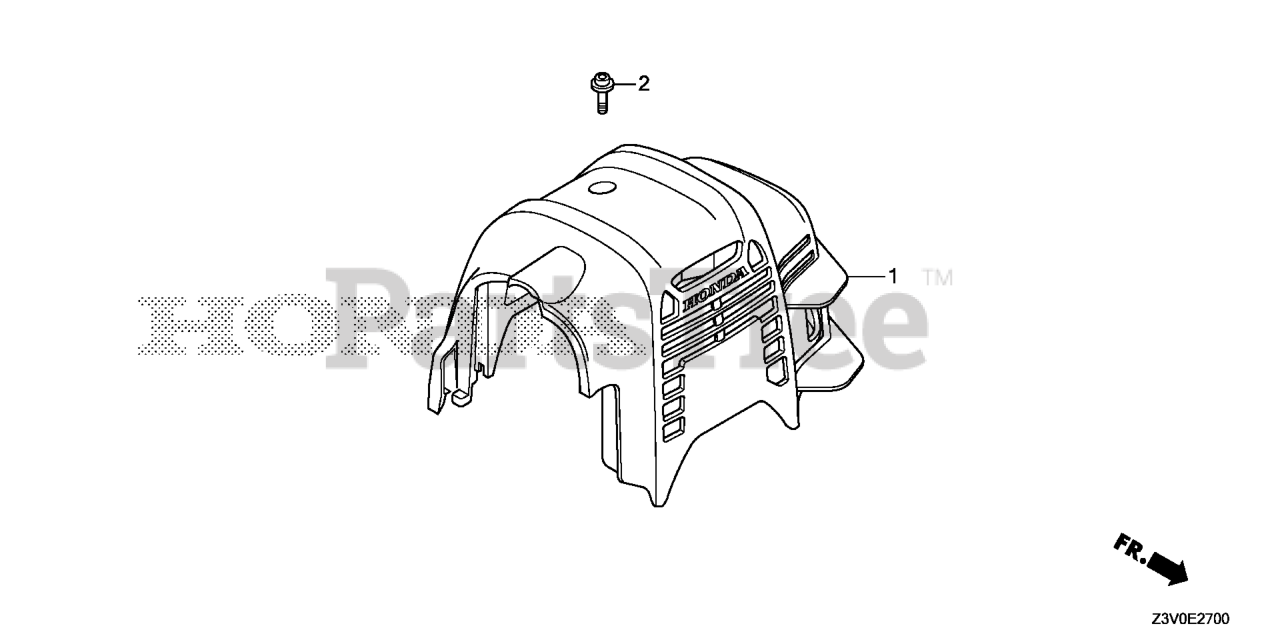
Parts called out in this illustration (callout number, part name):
1	COVER, TOP *R280* (POWER RED)
1	COVER, TOP *NH1* (BLACK)
2	BOLT, TOP COVER
